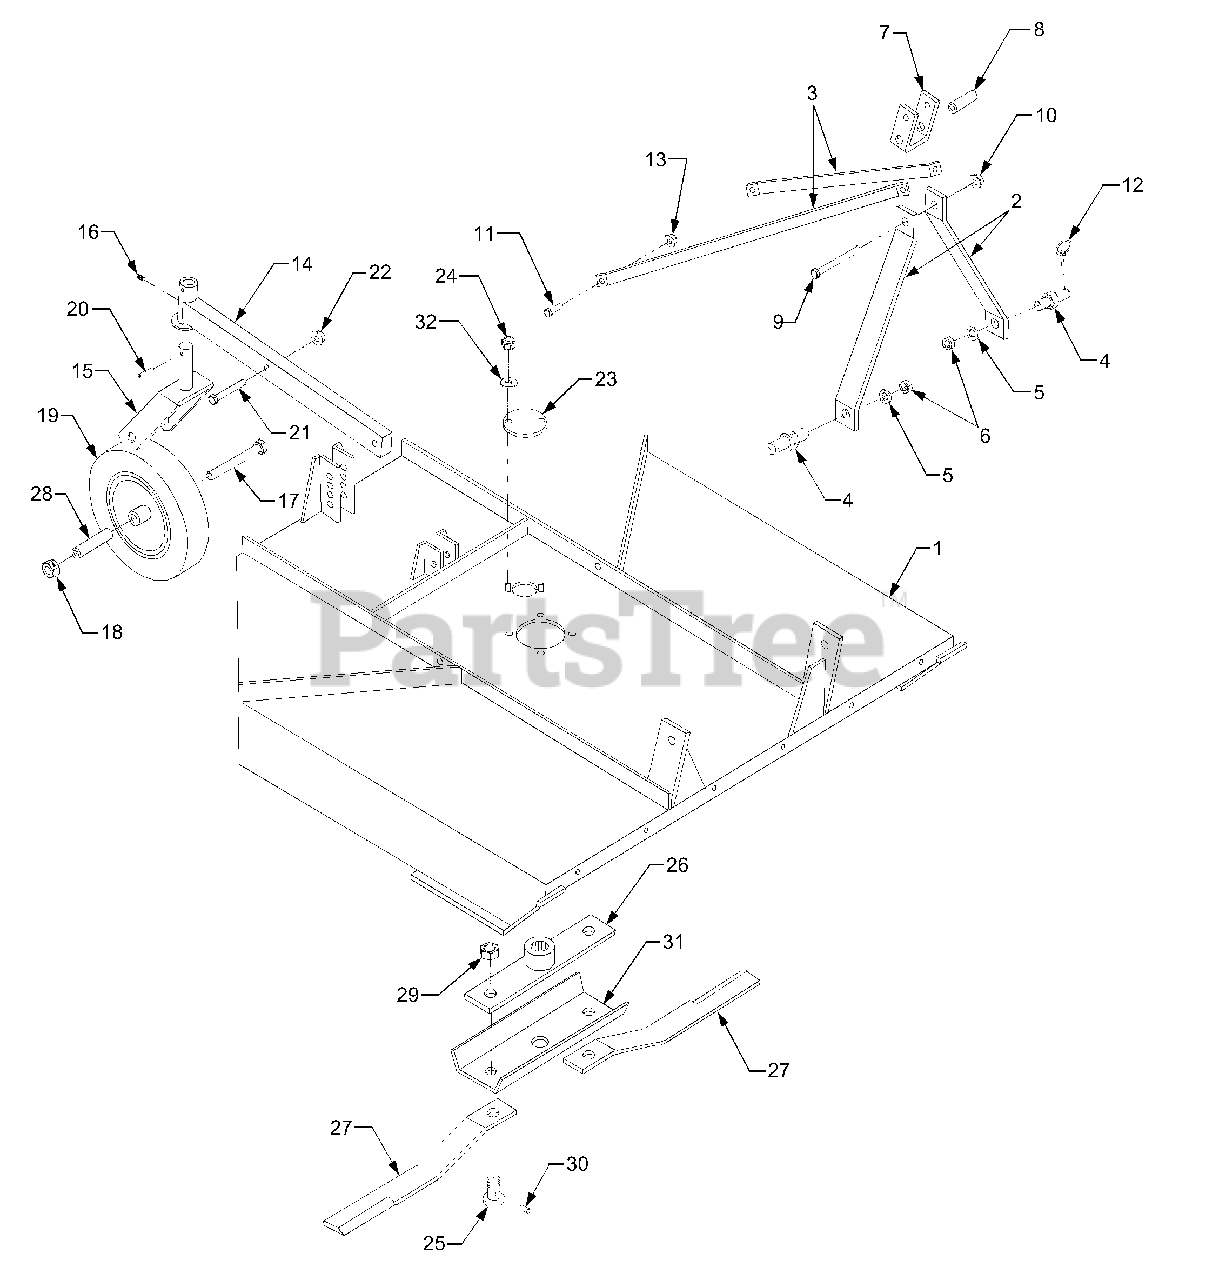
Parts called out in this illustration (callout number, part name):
1	Frame Complete
2	Vertical Support
3	Horizontal Support
5	Hex Nut, 5/8
6	Lock Washer, 5/8
7	Top Hitch Plate
8	Inner Spacer
9	Bolt, 5/8 x 7.0
10	Stover Nut, 5/8
11	Bolt, 14mm x 40
13	Stover Nut 14mm
16	Grease Fitting
17	Bolt, 3/4 x 7.0
18	Jam Nut, 3/4
19	Laminated Tire
20	Roll Pin, 10mm x 40
21	Bolt, 16mm x 90
22	Stover Nut, 16mm
23	Access Plate
24	Nylon Insert Lock Nut, 10mm
26	Blade Rotor w/Bushing
27	Blade
28	Wheel Spacer
31	Stump Jumper
32	Flat Washer, 10mm
